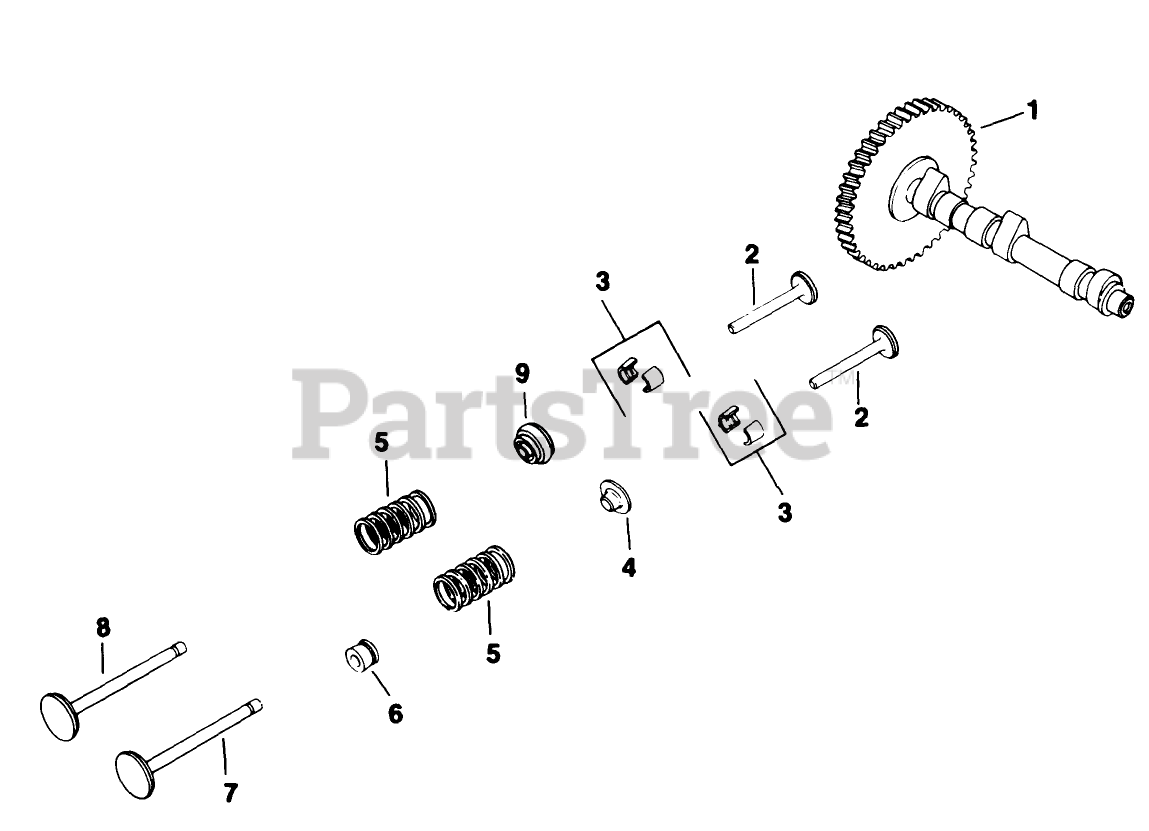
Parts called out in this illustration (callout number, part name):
1	Camshaft
2	Tappet
4	Retainer-Spring
5	Spring-Valve
6	Seal-Valve Stem
7	Valve-Intake
8	Valve-Exhaust
9	Rotator
